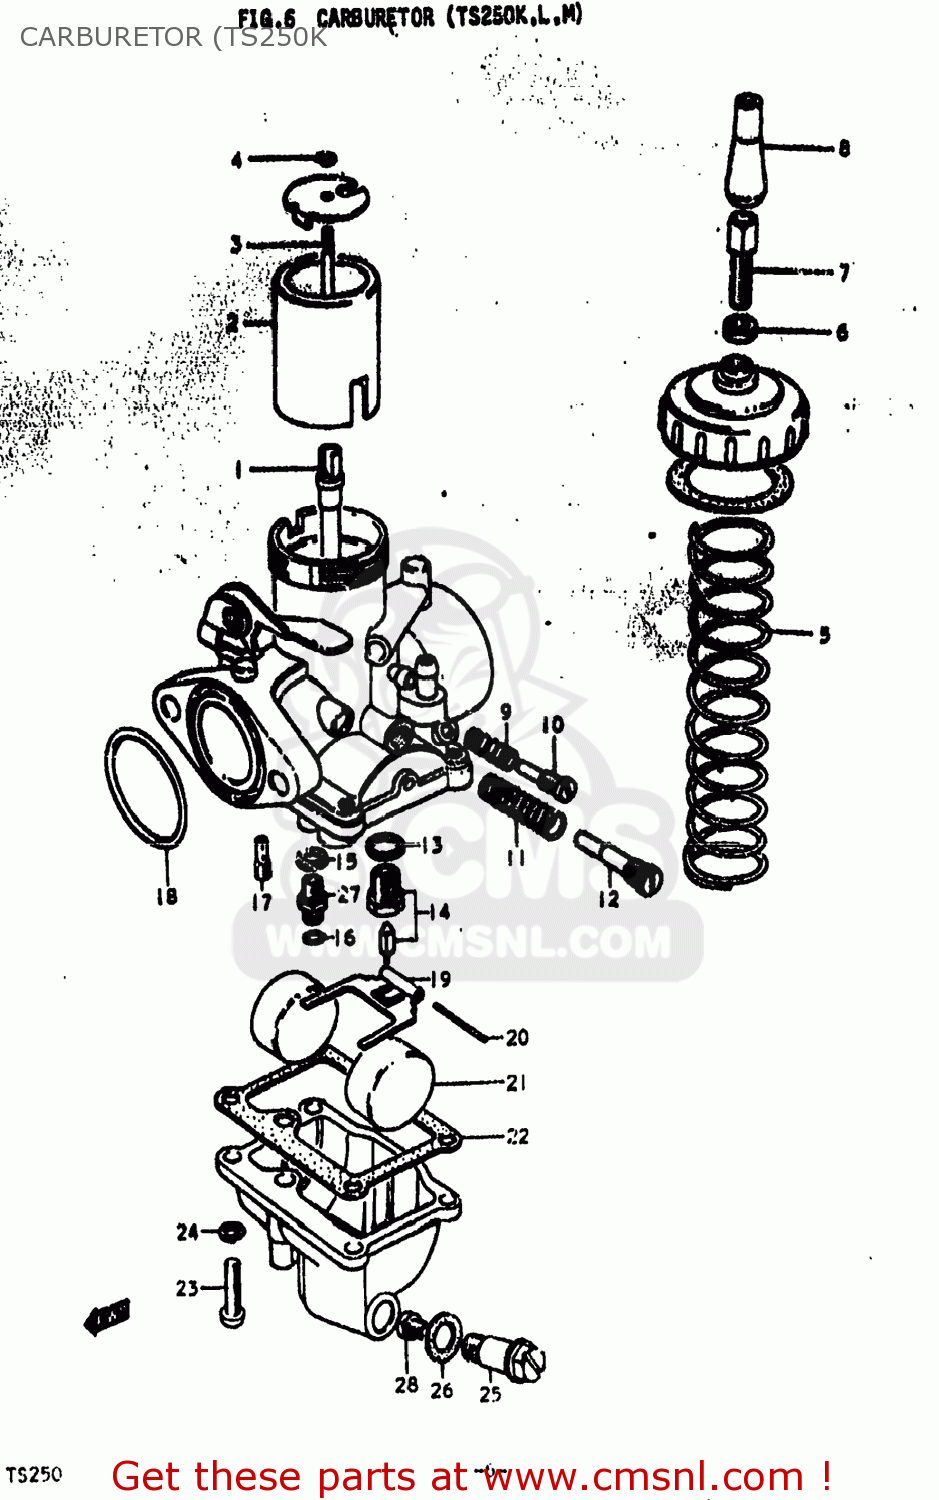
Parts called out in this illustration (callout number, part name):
1	JET,NEEDLE
2	VALVE,THROTTLE
3	NEEDLE,JET(5CN3)
4	CLIP
5	SPRING
6	NUT
7	ADJUSTER,CABLE
8	CAP
9	SPRING
10	SCREW,PILOT AIR
11	SPRING,THROTTLE SCREW
12	ADJUSTER
13	GASKET,VALVE SEAT (NAS)
14	VALVE ASSY,NEEDLE
15	WASHER
16	O-RING
17	JET
18	O-RING
19	ARM,FLOAT
20	PIN,FLOAT
21	FLOAT
22	GASKET,FLOAT CHAMBER (MCA)
23	SCREW
24	LOCK WASHER
26	WASHER
28	JET
